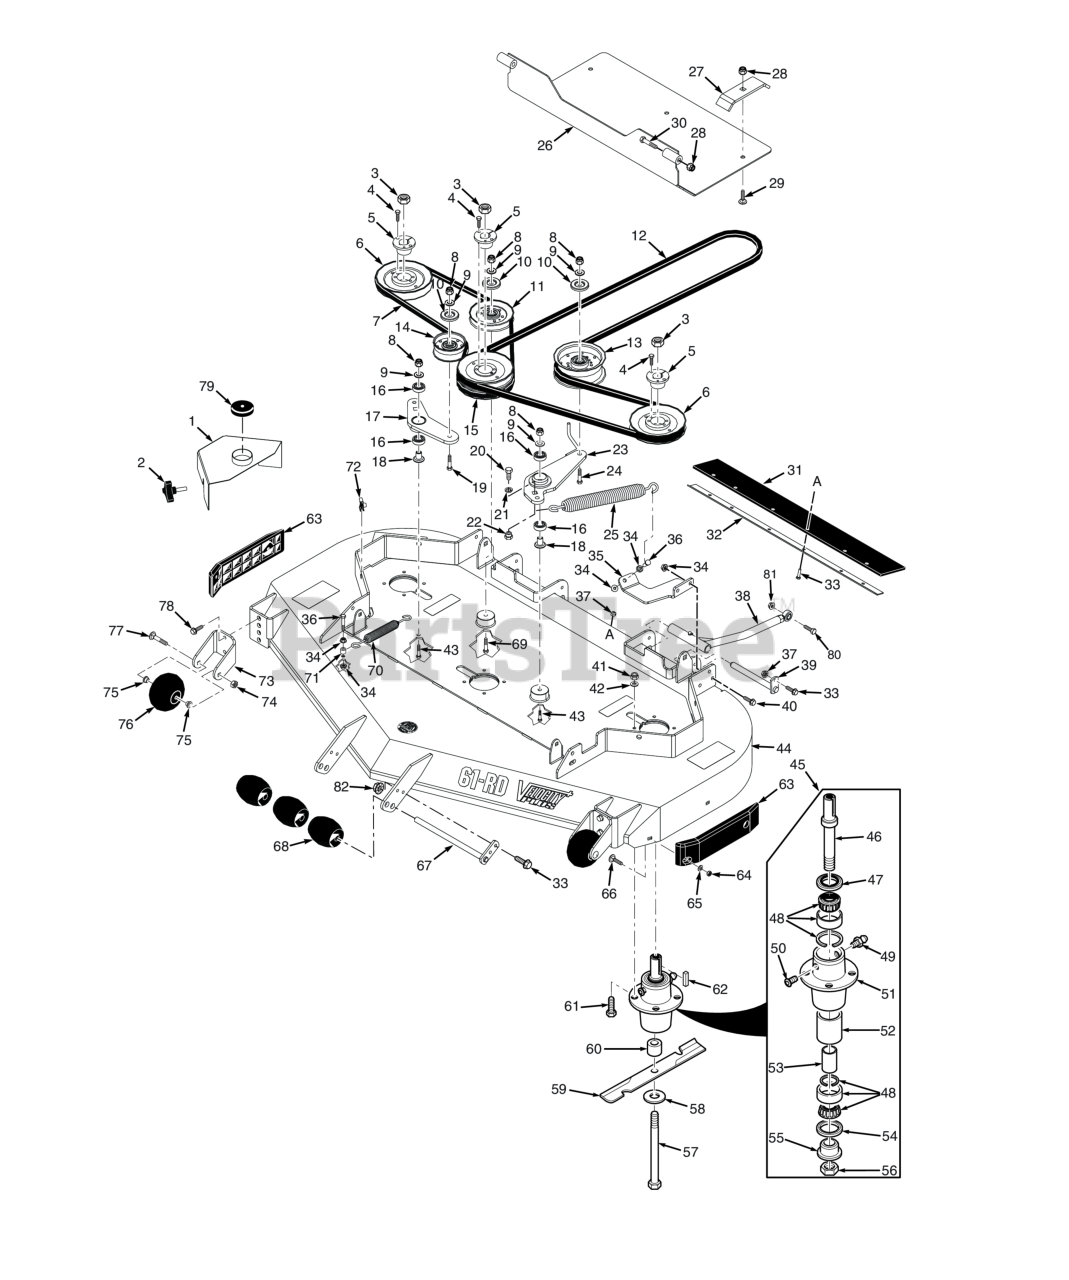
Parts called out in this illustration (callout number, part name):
1	Belt Cover, LH (INCL 85)
1	Belt Cover, RH (INCL 85)
2	Knob, w/stud 3/8-16 x 1-1/4"
3	Hex Locknut, Elastic Stop, 3/8-16
4	Bolt, Hex Head 1/4-20 x 1" Grade 8 Black
5	Hub, Tapered 1-1/8" Bore
6	Pulley, Tapered Bore 6.33" Dia.
7	Belt, Deck Drive R.H.
8	HEX NUT, ELASTIC STOP LOCK, 3/8-16
9	Flatwasher, 3/8 (.391 x .938 x .105 HD) Grade 8
10	Quick Pin, 5/16" Dia.
11	IDLER PULLEY, "V" GROOVE
12	Belt, Cutter Deck Drive - Cat
13	Pulley, Idler 5" Dia.
14	Pulley, 3-1/2" Dia.
15	Pulley, Double Groove 6.33" Dia.
16	BEARINGS, BALL, NEUTRAL RETURN
17	ldler Arm Assembly, R.H. Drive
18	Pivot, Idler Short
19	Capscrew, Hex Head 3/8-16 x 2-1/2"
20	Bolt, Hex Head 7/16-14 x 1"
21	Lockwasher, 7/16� Spring
22	Boss, Spring Anchor - LH
23	Idler Arm
24	Bolt, Hex Head 3/8-16 x 3" - 52"
25	Spring, L.H. Deck Drive
26	Weldment, Debris Shield
27	Mounting Bracket, Shield
28	HEX NUT, ELASTIC STOP LOCK, 5/16-18
29	Bolt, Carriage 5/16-18 x 1-1/2"
30	Bolt, Hex Head, 5/16-18 x 2.75 Zinc.
31	Pad, Rubber
32	Retaining Plate, Pad
33	Bolt, Heax Head 5/16-18 x 1" (48V / 52V)
34	NUT, 3/8-16 SERRATED FLANGE HEX HEAD
35	Spring Mount, SMCZ
36	Bolt, Hex Head 3/8-16 x 1-1/2" Grade 8 Black
37	HEX NUT, ELASTIC STOP LOCK, 5/16-18
38	Pusharm Assembly, LH
38	Pusharm Assembly, RH
39	Shaft Weldment, Pusharm
40	Bolt, Hex Head, 3/8-16 x 1 Gr. 5
41	Lock Nut, 5/16-18 Elastic Stop Grade 8
42	Lockwasher, 5/16 (.317 x .586 x .078) Helical Spring
43	Bolt, Hex Head 3/8-16 x 3" - 52"
44	Cutter Deck Assembly w/Decals SCZII-61RD
45	Cutter Spindle Assembly
46	Spindle Shaft, Tapered Brng
47	SEAL, 2.00 O.D. X 1.50 BORE
48	Tapered Bearing Set (Two Bearings W/Race)
49	GREASE FITTING, STR. 1/4-28 SELF TAP.
50	RELIEF FITTING, TAPERED BEARING SPINDLE
51	Housing, Spindle
52	Spacer, Outside, Cutter Spindle
53	SLEEVE, CUTTER SPINDLE
54	Seal, 2.00" O.D. x 1.625" Bore
55	SPINDLE BUSHING, BOTTOM
56	Nut , Spec ial 1 -1/ 1 6 - 1 8
57	BOLT, HEX HEAD, 5/8-11 X 9-1/2 GR.5
58	Flatwasher, 5/8-.688 x 1-3/4 x .134 HD
59	Cutter Blade, 21" (35BV & 37BV-EFI)
60	Spacer, Spindle Bottom
61	Bolt, Hex Head 5/16-18 x 1-3/4" Grade 8
62	Key, 1/4 x 1/4 x 2.0"
63	Pad, Deck Wear
64	Nut, Center Lock, 5/16-18(32)
65	Flatwasher, 5/16-.344 x .688 x .065 (48V / 52V)
66	Bolt, 5/16-18 x .75 RHSN Carriage
67	Shaft Weldment, Guide Roller
68	Wheel, Anti-Scalp
69	Bolt, Hex Head 3/8-16 x 2-1/4" - 61"
70	Spring, RH Deck Drive
71	SPACER, IDLER
72	U-Nut, 3/8-16
73	Bracket, Anti-Scalp Wheel
74	Bolt, Hex Head 3/8-16 x 1" Ser. Flg.
75	Bushing, .376" I.D. Oilite
76	Bolt, Carriage 3/8-16 x 4"
77	Bolt, Hex Head 3/8-16 x 3-1/2"
78	Capscrew, 3/8-16 x 1.0" Serrated Flange Hex Hd
81	Nut, Center Lock 5/8-11
82	Nut, Flange Head Elastic Stop 5/16-18
